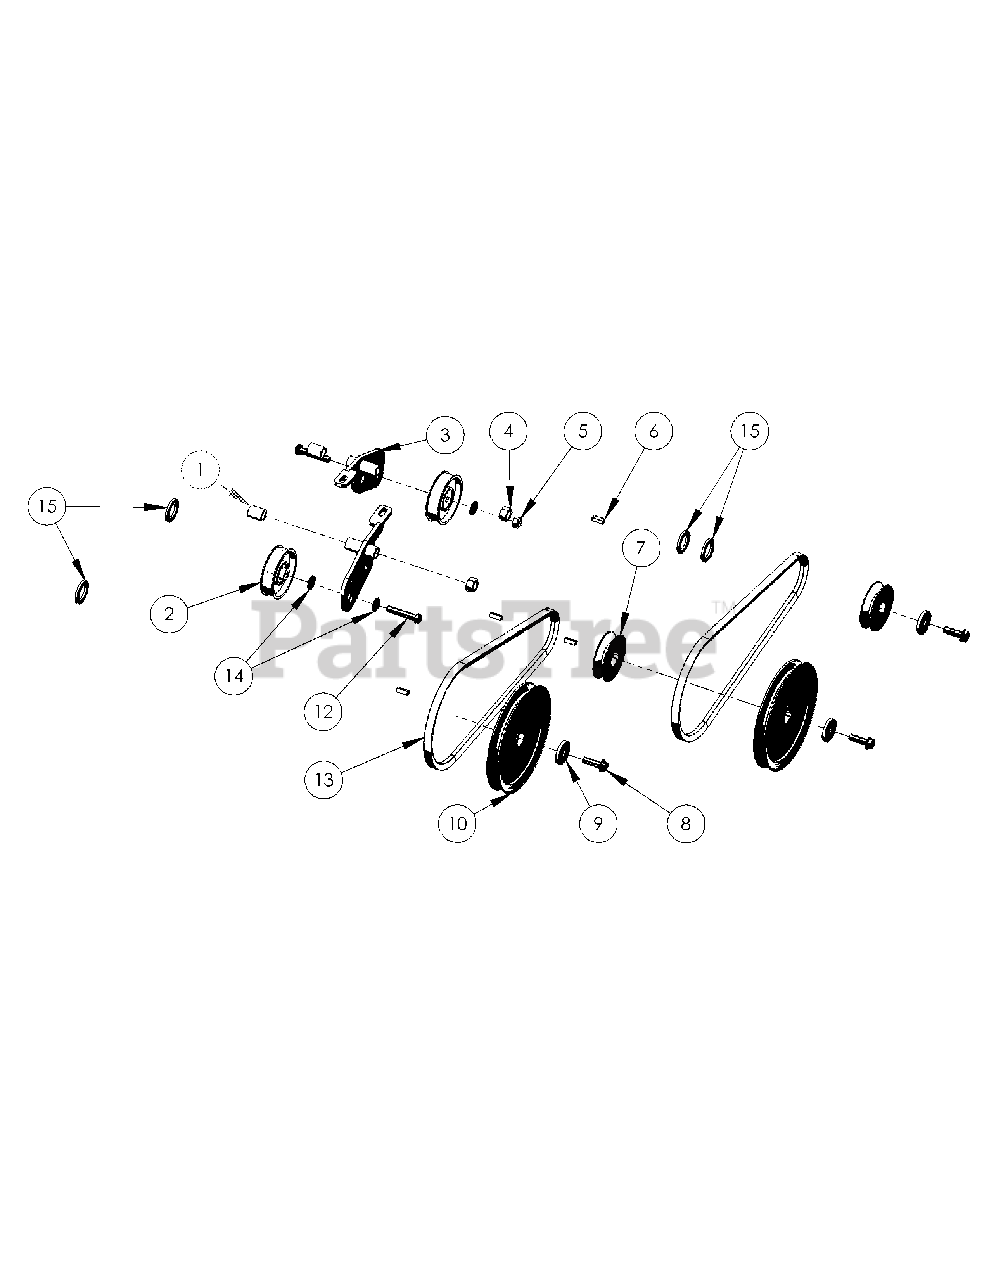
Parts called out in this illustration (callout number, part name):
1	CTC2 Idler Spacer
3	CTC2 Idler Assembly
4	1/2-13 Nylon Insert Nut
5	3/8-16 Nylon Insert Nut
6	Key 1/4 Sq X .75
7	Pulley 1" Bore
8	Cap Screw Serrated Flange 3/8-16 X 1.25
9	Flat Washer, .39 Id X 1.5 Od X .188", Yz
10	Pto Driven Pulley
11	5/16" Flat Washer
12	Cap Screw 3/8-16 X 2.00
13	Belt A38(4L400)
14	Detent Pin 3/8" X 1 5/8 El
15	Offset Washer
